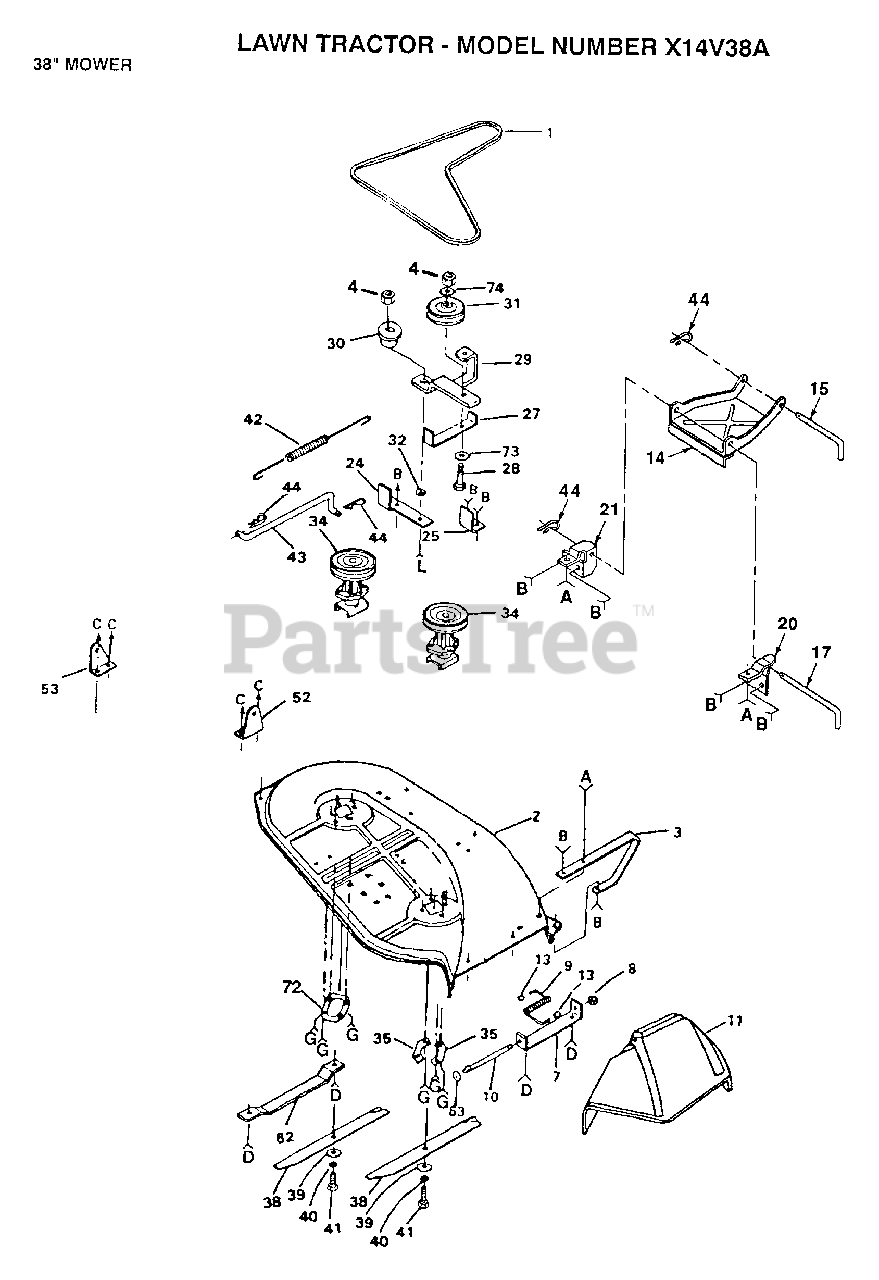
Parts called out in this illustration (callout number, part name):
1	BELT-V.79.1.MWR
8	NUT PUSH M
10	ROD-HINGE T
11	DEFLECTOR-SHLD T
13	CAP-SLEEVE LT
14	"STOP, LINK PARAL"
15	"ROD, FRT. PARAL T"
17	HINGE PIN T
20	BRACKET RH LT
21	BRACKET LH T
24	SUPPORT ARM T
25	STOP T
28	BOLT
30	SPACER RETAINER
32	"WASHER, WEAR LT"
34	"JACKSHAFT.38""LT"
35	SUPPORT PLATE LT
38	"BLADE.38"" HI-LI"
39	WASHER
41	BOLT.3/8-24X1-1/2
42	"SPRING.EXT.8.5"""
44	SPRING.RETAINER
52	"BRKT,SUSP RH T"
53	"BRKT,SUSP REAR LH"
62	RUNNER-LH M
63	WASHER
72	SUPPORT T
73	WASHER
74	WASHER
